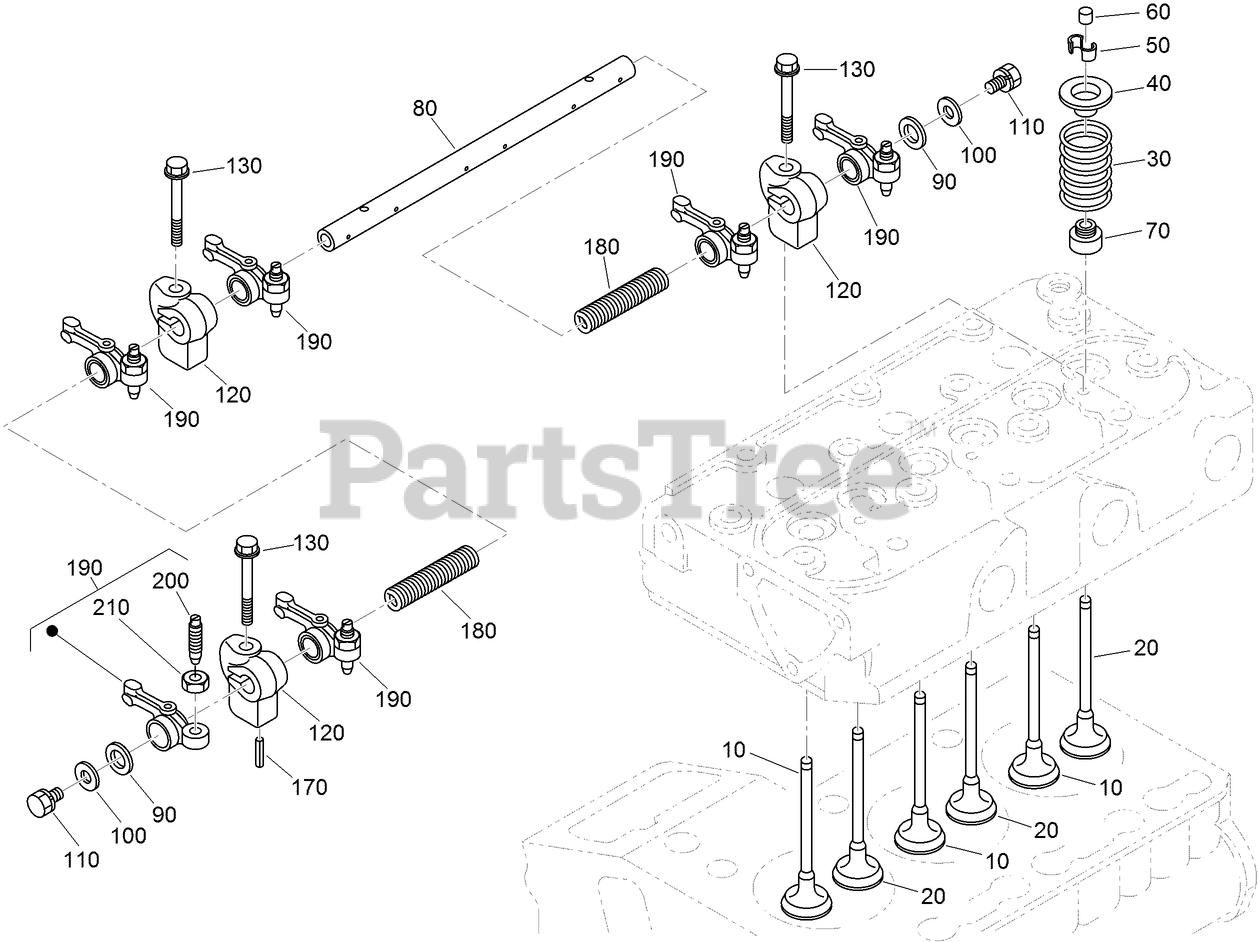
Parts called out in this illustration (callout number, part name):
10	VALVE-INLET
20	VALVE-EXHAUST
30	SPRING-VALVE
40	RETAINER-SPRING, VALVE
50	COLLET-SPRING, VALVE
60	CAP-VALVE
70	SEAL-STEM, VALVE
80	SHAFT-ARM, ROCKER
90	WASHER
100	WASHER-PLAIN
120	BRACKET-ARM, ROCKER
130	BOLT-FLANGE
170	PIN-SPRING
180	SPRING
190	ROCKER ARM ASM
200	SCREW-ADJUSTING
